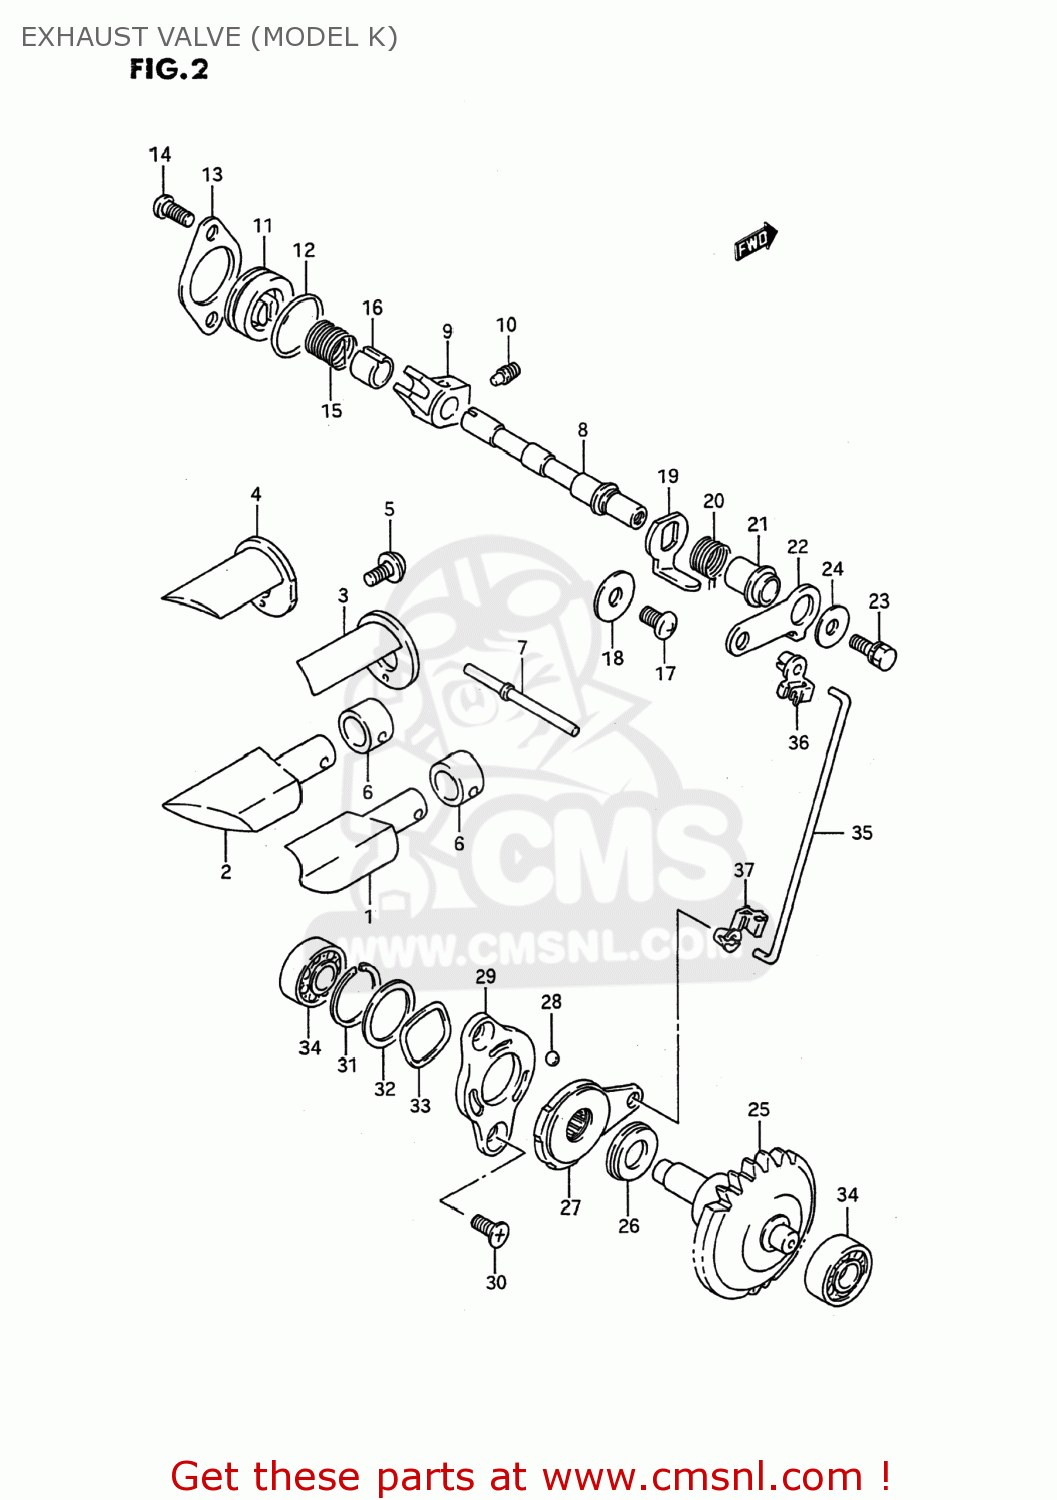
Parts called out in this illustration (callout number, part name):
1	VALVE,EXHAUST,RIGHT
2	VALVE,EXHAUST,L
3	GUIDE,EXHAUST VALVE,R
4	GUIDE,EXHAUST VALVE,L
5	SCREW
6	HOLDER,EXHAUST VALVE
7	PIN,EXHAUST VALVE 48.5MM
8	SHAFT,EXHAUST VALVE
9	ARM,EXHAUST VALVE SHAFT
10	SCREW(6X10)
11	CAP,EXHAUST VALVE
12	O RING(D:1.9,ID:22.6)
13	RETAINER,EXHAUST VALVE
14	SCREW
15	SPRING
16	SPACER,EXHAUST VALVE SPRING
17	SCREW
18	WASHER
19	LEVER,EXHAUST VALVE NO
20	SPRING
21	SPACER,EXHAUST VALVE
22	LEVER,EXHAUST VALVE NO
23	BOLT
24	WASHER (5.5X16X1.2)
25	GOVERNOR ASSEMBLY,EXHAUST
26	BEARING(10X22X2.8)
27	ACTUATOR,EXHAUST VALVE
28	BALL
29	STARTER,EXHAUST VALVE ACTUATOR
30	SCREW(5X10)
31	CIRCLIP
32	SHIM(19.1X25X0.3)
33	WASHER
34	BEARING(8X22X7)
35	ROD,EXHAUST VALVE
36	BUSH,EXHAUST VALVE ROD NO.1
37	BUSH,EXHAUST VALVE ROD NO.2
